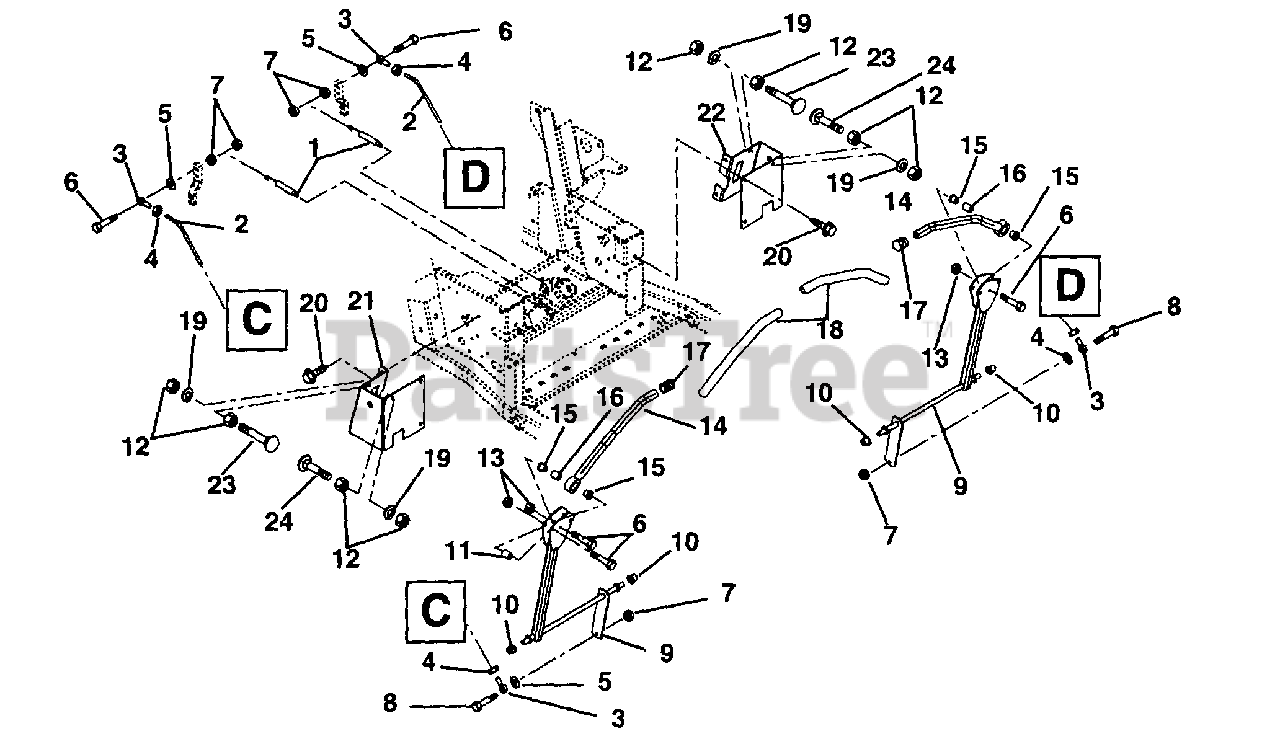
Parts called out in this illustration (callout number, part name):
1	SG-TENS .062X.56X8.0 WLD 11
2	ROD - STEERING ADJUSTMENT
3	ROD END, 5/16 RH - FEMALE
4	NUT-JAM .31-24 YWZC
5	@WSHR-LK .31X.078 REG YWZC
6	@BLT-HEX .31-18X1.75 GR5 YWZC
7	@NUT-LK-CTR .31-18 YWZC
8	@BLT-HEX .31-18X1.50 GR5 YWZC
9	ROD - STEERING
10	BSHG-FLG .515X.750X.745X1.00NY
11	ECCENTRIC
12	@NUT-HEX .38-16 YWZC
13	@NUT-LK-CTR .31-18 YWZC
14	HANDLE WLDMT LH
15	BSHG-FLG .762X1.48X.44 NYL
16	SPACER .328 X .76 X 1.01
17	CAPLUG - HANDLEBAR
18	GRIP - HANDLEBAR
19	@WSHR-LK .38X.094 REG YWZC
20	@SCR-TAP .38-16X.75 HWH TR YWZ
21	MOUNT,STEERING ROD RH (ORANGE)
22	MOUNT,STEERING ROD LH - ORANGE
23	@BLT-RDHDSQNK .38-16X2.00 G2YZ
24	@BLT-RDHDSQNK .38-16X1.50 G2YZ
